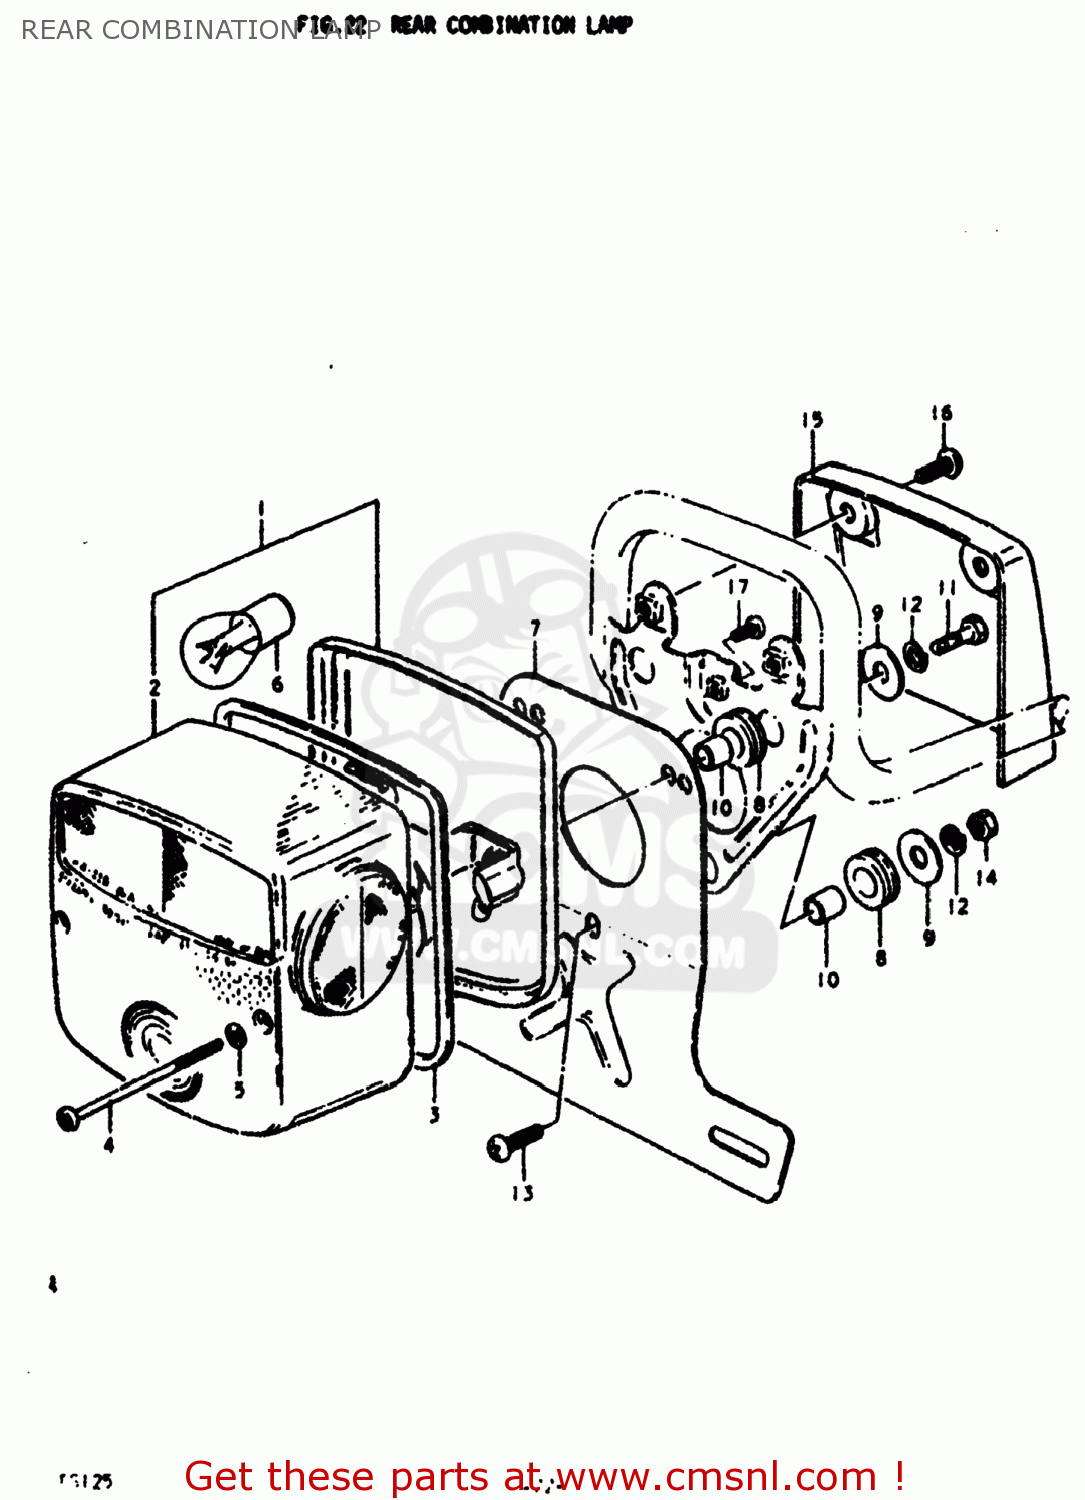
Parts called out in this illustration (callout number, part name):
1	LAMP ASSEMBLY,REAR COMBINATION
2	LENS,REAR COMBINATION LAMP
3	GASKET (NAS)
4	SCREW
5	GASKET (NAS)
6	BULB(6V32/3CP,STANLEY)
7	BRACKET,LICENSE PLATE
8	CUSHION
9	WASHER (6.5X24X1.6)
10	SPACER,REAR COMBINATION LAMP
11	BOLT
12	LOCK WASHER
13	SCREW
14	NUT
15	COVER
16	SCREW 6X12
17	SCREW
